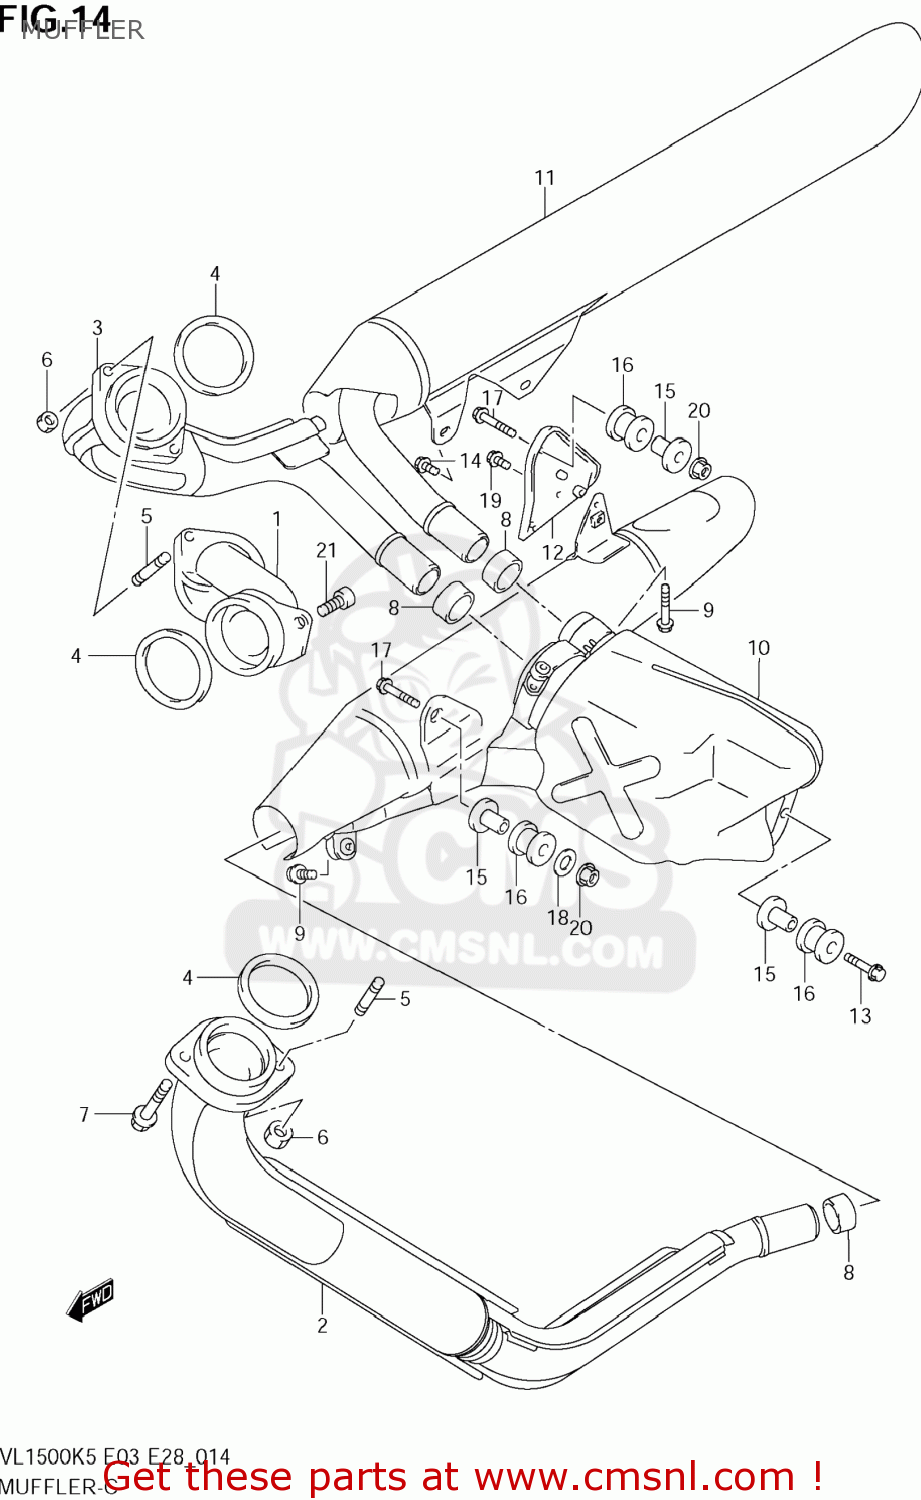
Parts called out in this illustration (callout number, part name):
1	MANIFOLD,EXHAUST RR
2	PIPE,EXHAUST,R
3	PIPE,EXHAUST,L
4	GASKET,EXHAUST PIPE (NAS)
5	BOLT,STUD
6	NUT
7	BOLT(8X25)
8	CONNECTOR,MUFFLER
9	BOLT(8X33)
10	MUFFLER,R
11	BODY,MUFFLER,L
12	BRACKET,MUFFLER SUPPORT
13	BOLT 8X45
14	BOLT
15	SPACER(8.6X12X27.1)
16	CUSHION
17	BOLT(8X42)
18	WASHER(8.5X33X1.5)
19	BOLT(10X20)
20	NUT
21	BOLT
